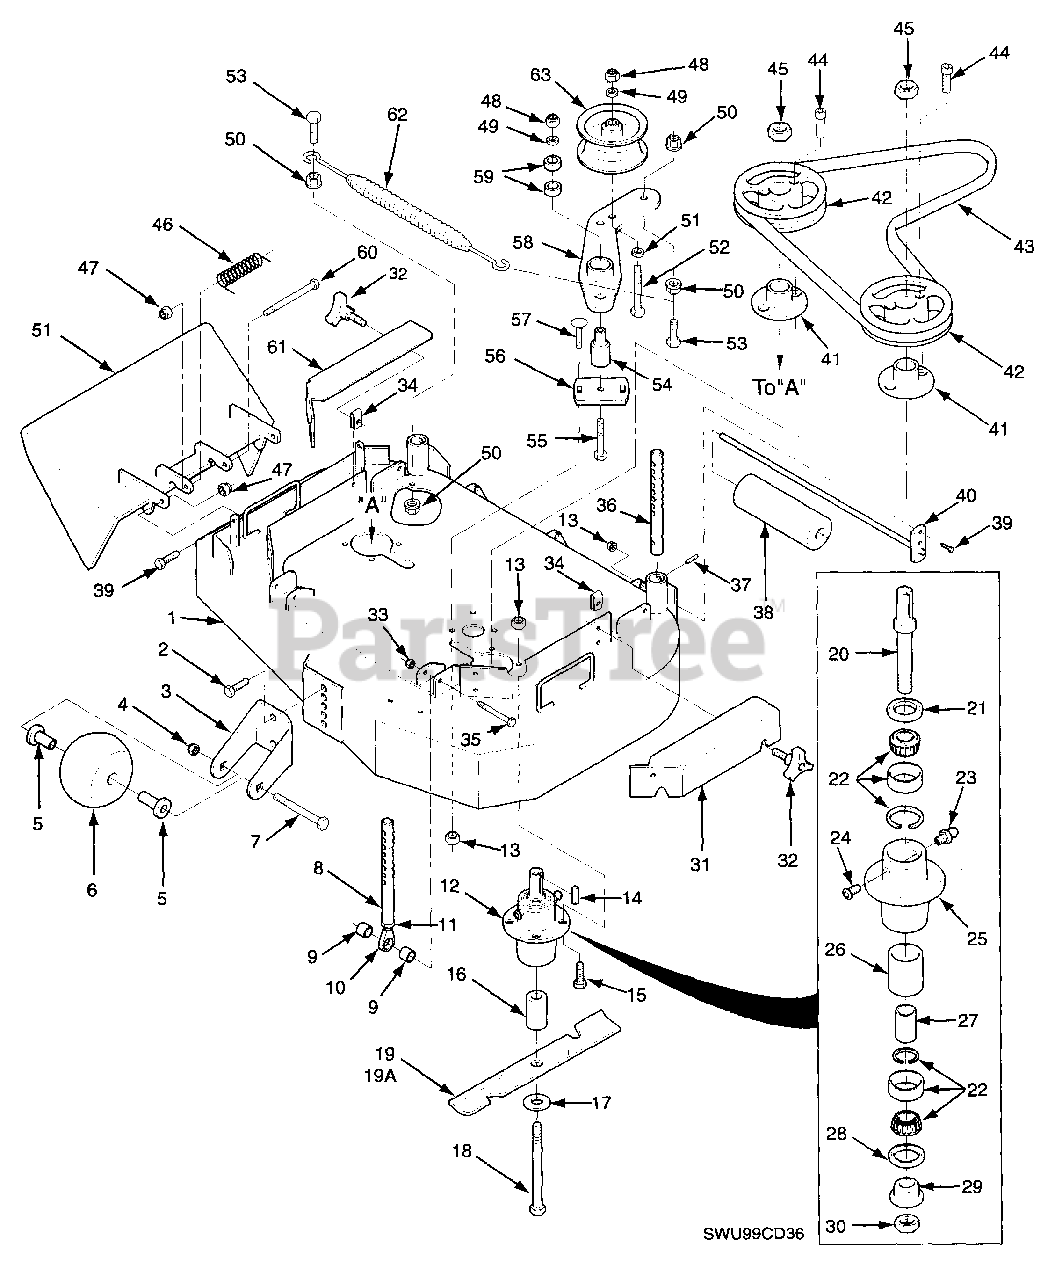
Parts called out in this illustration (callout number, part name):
1	Cutter Deck
2	Capscrew, 3/8-16 x 1.0" Serrated Flange Hex Hd
3	Bracket, Anti-Scalp Wheel
4	Lock Nut, 3/8-16 Center Lock
5	Bushing, 376 ID Oilite
6	Wheel, Anti-Scalp
7	Bolt, Carriage 3/8-16 x 4.0"
8	Pin Assy., Deck Adj.
9	Spacer, Deck Adjustment Pin
10	Rod End, Male 3/8-24 RH Thread
11	Nut, 3/8-24 Jam
12	Spindle Assembly
13	Nut, 5/16-18 Serrated Flange
14	Key,1/4 x 1/4 x 2.0"
15	Bolt, Hex Head 5/16-18 x 1.25"
16	Spacer, Spindle
17	Flatwasher, 5/8 W
18	Bolt, Hex Head 5/8-11 x 9.50"
19	Cutter Blade, 18"
19A	Cutter Blade, 18" Hi Lift
20	Spindle Shaft
21	Seal, Cutter Spindle Top
22	Tapered Bearing Set
23	Grease Fitting
24	Relief Fitting, Cutter Spindle
25	Spindle Housing
26	Spacer, Outside
27	Spacer, Inside
28	Seal, Cutter Spindle Bottom
29	Spindle Bushing
30	Nut, Spindle
31	Belt Cover, LH
32	Wing Nut, 3/8-16
33	Nut, 3/8-16 Elastic Stop
34	U-Nut, 3/8-16
35	Bolt, Hex Head 3/8-16 x 2.50"
36	Pin, Deck Adj. Rear
37	Pin, Sloted Spring 3/16 x 1.50"
38	Guide, Roller
39	Bolt, Hex Head 5/16-18 x 1.0"
40	Roller Shaft
41	Tapered Hub
42	Pulley
43	Belt, Cutter Deck
44	Capscrew, Socket Head. 1/4-20 x 1.375"
45	Hex Nut, 5/8-11
46	Spring, Chute Return
47	Hex Nut, 5/16-18 Elastic Stop
48	Hex Nut, 3/8-16 Elastic Stop
49	Flatwasher, 3/8 (.938 x .391 x .105)
50	Nut, 3/8-16 Serrated Flange
51	Discharge Chute
52	Capscrew, Hex Head 3/8-16 x 3.75"
53	Capscrew, Hex Head 3/8-16 x 1.50"
54	Pivot, Idler - Long
55	Capscrew, Hex Head 38/16 x 3.25"
56	Base, Idler Pivot
57	Bolt, Carriage 5/16-18 x 1.0"
58	Idler Arm Weldment
59	Ball Bearing
60	Bolt, Hex Head 5/16-18 x 4.25"
61	Belt Cover, RH
62	Spring, Deck Idler
63	Pulley, Idler
